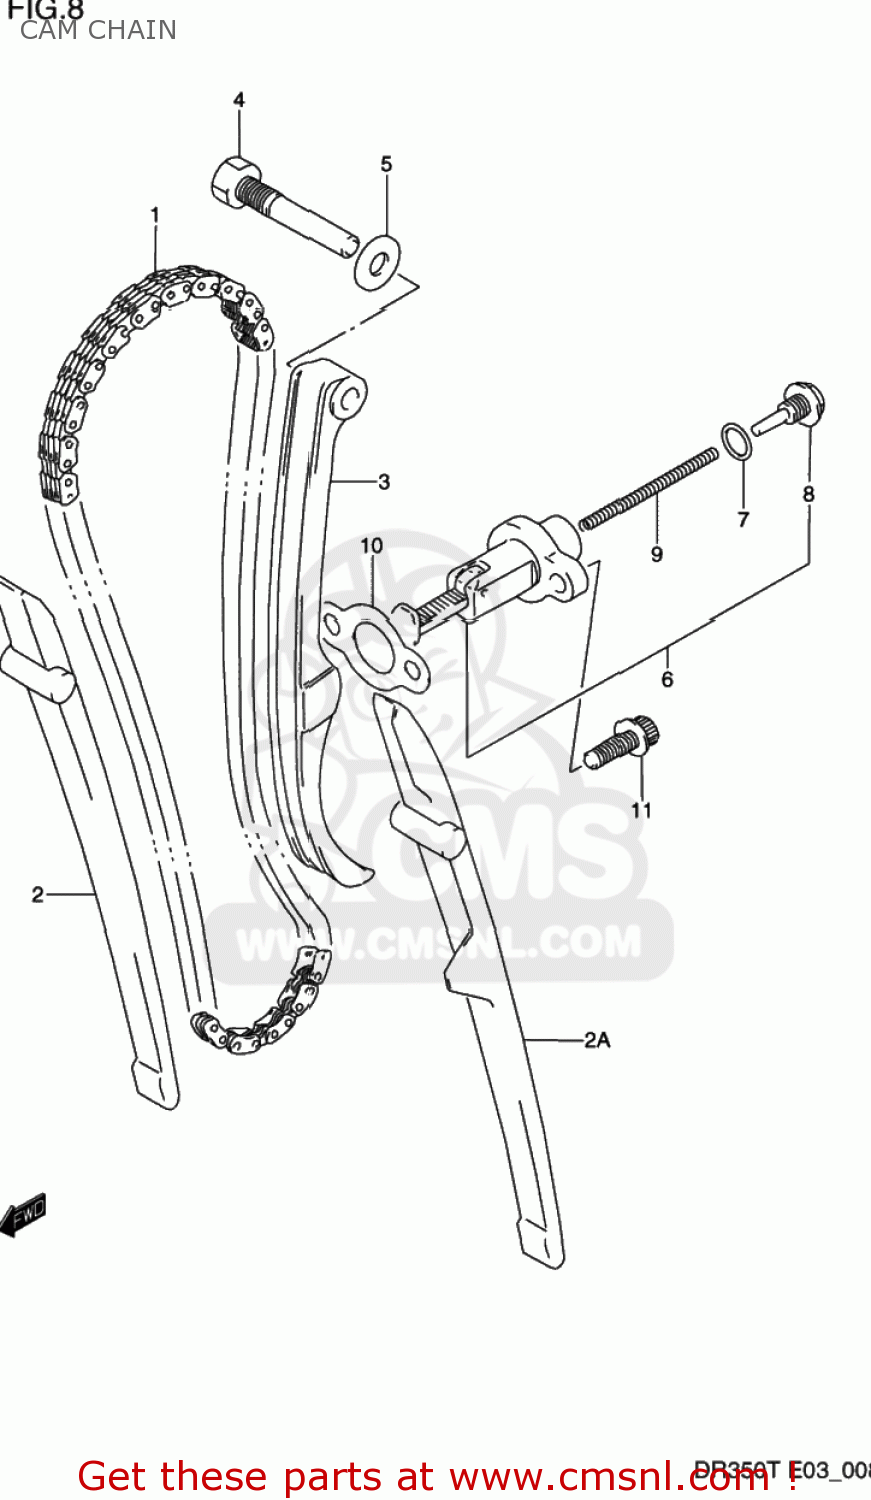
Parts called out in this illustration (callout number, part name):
1	CHAIN,CAMSHAFT DRIVE
2	GUIDE,CAM CHAIN
2A	GUIDE,CAM CHAIN
3	TENSIONER,CAM CHAIN
4	BOLT,CAM CHAIN TENSIONER
5	GASKET 8.2X14X1 (NAS)
6	ADJUSTER ASSY,TENSIONER
7	O RING
8	PLUG,ADJUSTER
9	SPRING
10	GASKET,TENSIONER ADJUSTER (NAS)
11	BOLT
